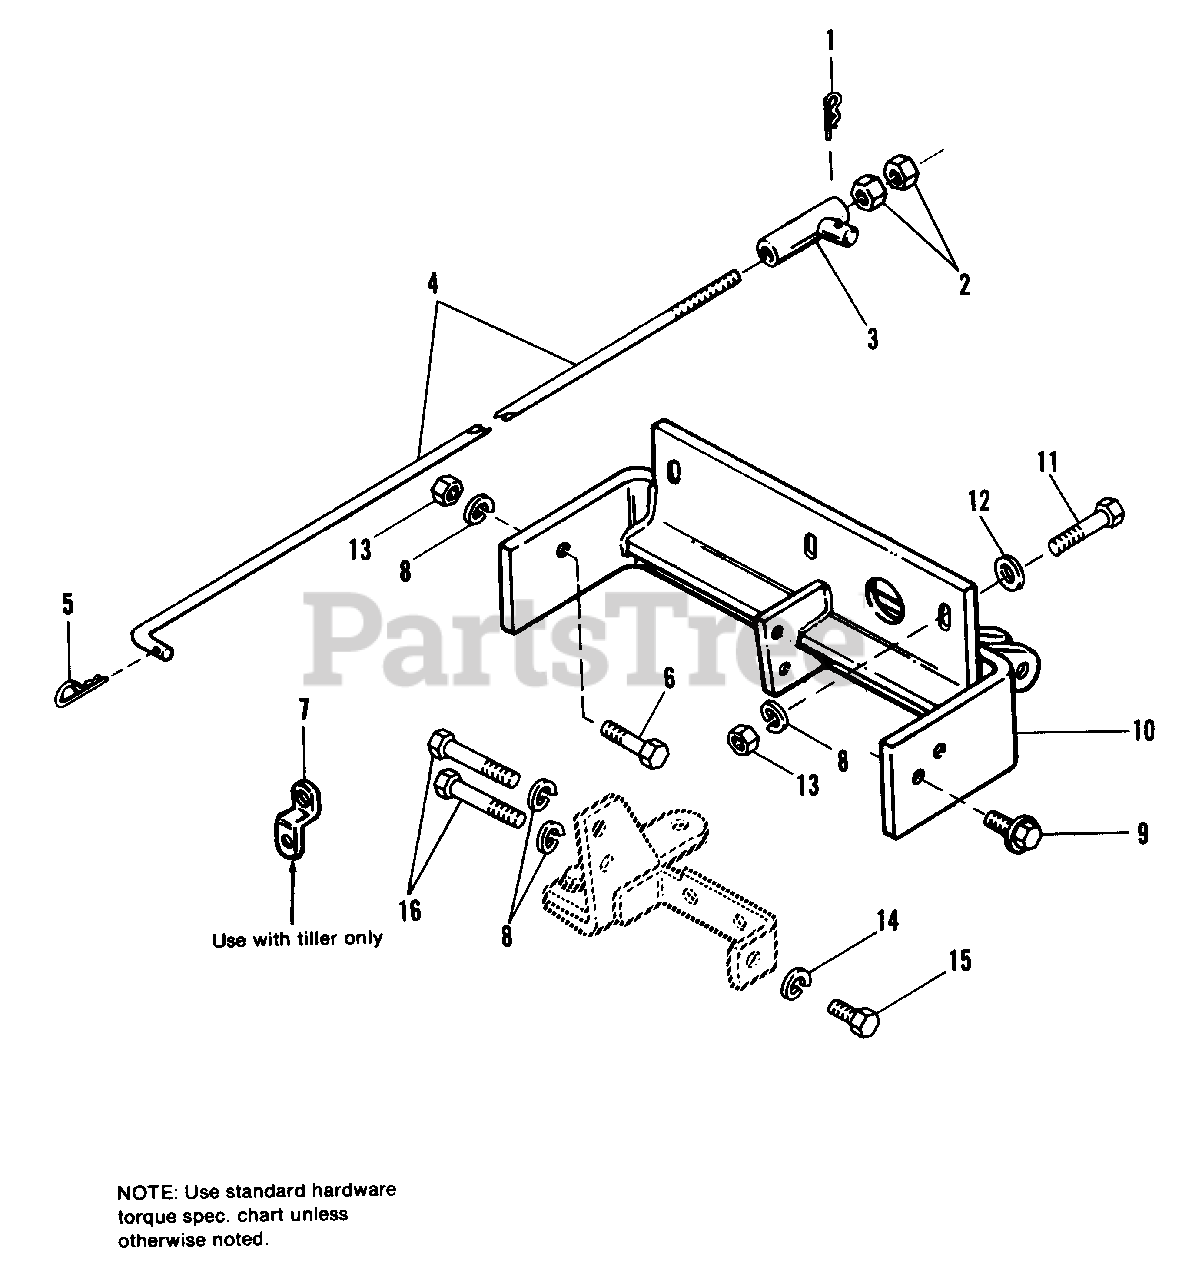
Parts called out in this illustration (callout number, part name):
1	PIN, Quick
2	NUT, Hex, Jam, 1/2 x 20
3	TUBE ASSY., Guide (6200 only)
4	ROD, Lift
5	CLIP, Hair Pin
6	CAPSCREW, Hex Hd., 3/8-16 x 7/8 (Qty. 1 on 62030)
7	CLIP, Spring (6200 only)
8	LOCKWASHER, 3/8
9	CAPSCREW, Hex, Whizlock, 3/8-16 x 1-1/4
10	HITCH ASSY.
11	CAPSCREW, Hex Hd., 3/8-16 x 1 (6200 Only)
12	WASHER, 3/8 (6200 only)
13	NUT, Hex, 3/8-16 (6200 only)
14	LOCKWASHER, 5/16 (6200 only)
15	CAPSCREW, Hex Hd., 5/16-18 x 1-1/2 (6200 only)
16	CAPSCREW, Hex Hd., 3/8-16 x 1-1/4 (6200 only)
